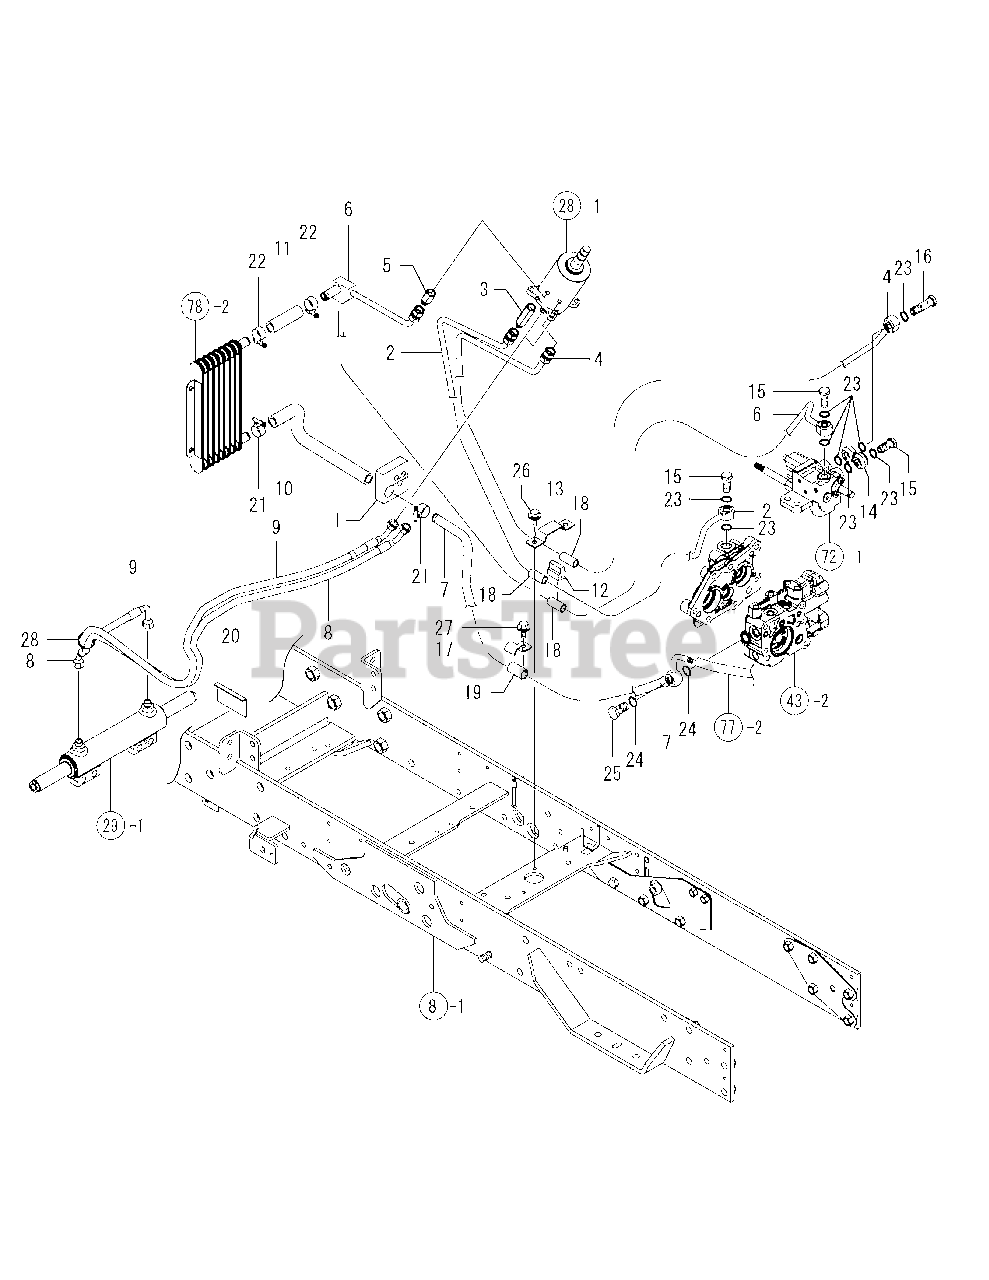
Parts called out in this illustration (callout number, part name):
2	HP PIPE, PUMP CMP
3	JOINT 9/16 UNF-70
4	HP PIPE, VALVE CMP
5	JOINT 9/16 UNF-40
6	LP PIPE, COOLER CMP
7	LP PIPE, TANK CMP
8	HP HOSE L, PST
10	LP HOSE A (OIL COOLER)
11	LP HOSE B (OIL COOLER)
14	CONNECTOR 9/16 UNF
15	BALL JOINT BOLT 9/16
16	BALL JOINT BT L 9/16
20	SEAL, WIRING HARNESS
23	GASKET 14, ROUND
26	BOLT M 8X 16 PLATED
27	BOLT M 8X 16 PLATED
